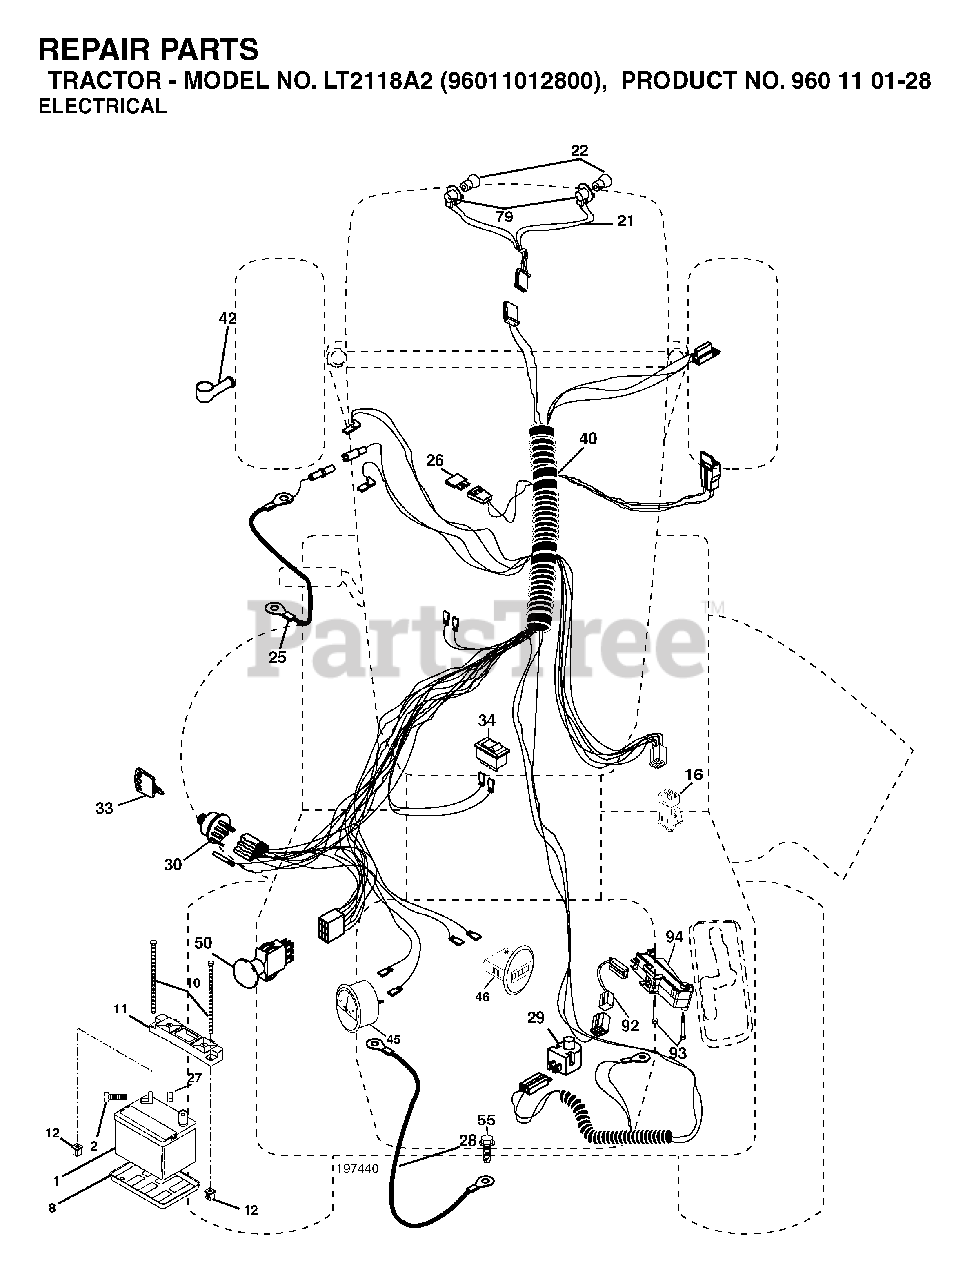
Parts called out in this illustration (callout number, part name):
1	BATTERY 12V .35 AMP
8	BATTERY TRAY T
10	BOLT 1/4-20 X 7.5
11	BATTERY HOLDDOWN
12	NUT, PUSH NYLON 1/4" BATTERY
16	SWITCH INTERLOOK PUSH-IN
21	HARNESS.W/LIGHT SOCKET
22	LIGHTBULB
26	FUSE 20AMP
27	NUT
28	CABLE GROUND 6 GA 21" 90T BLK
29	SWITCH.SEAT.DP W/RAMPS
30	SWITCH.IGN.DELTA.W.LGH.ROS
33	KEY MLD GEN DELTA
34	SWITCH LT
42	COVER.TERMINAL.RED
46	HOURMETER SNAP-IN
50	PTO SWITCH
55	SCREW LT
79	BULB HOLDER ASM.
92	HARNESS.PIGTAIL.CONSLE
93	SCREW.PLASTITE
94	MODULE.REVERSE.ROS
